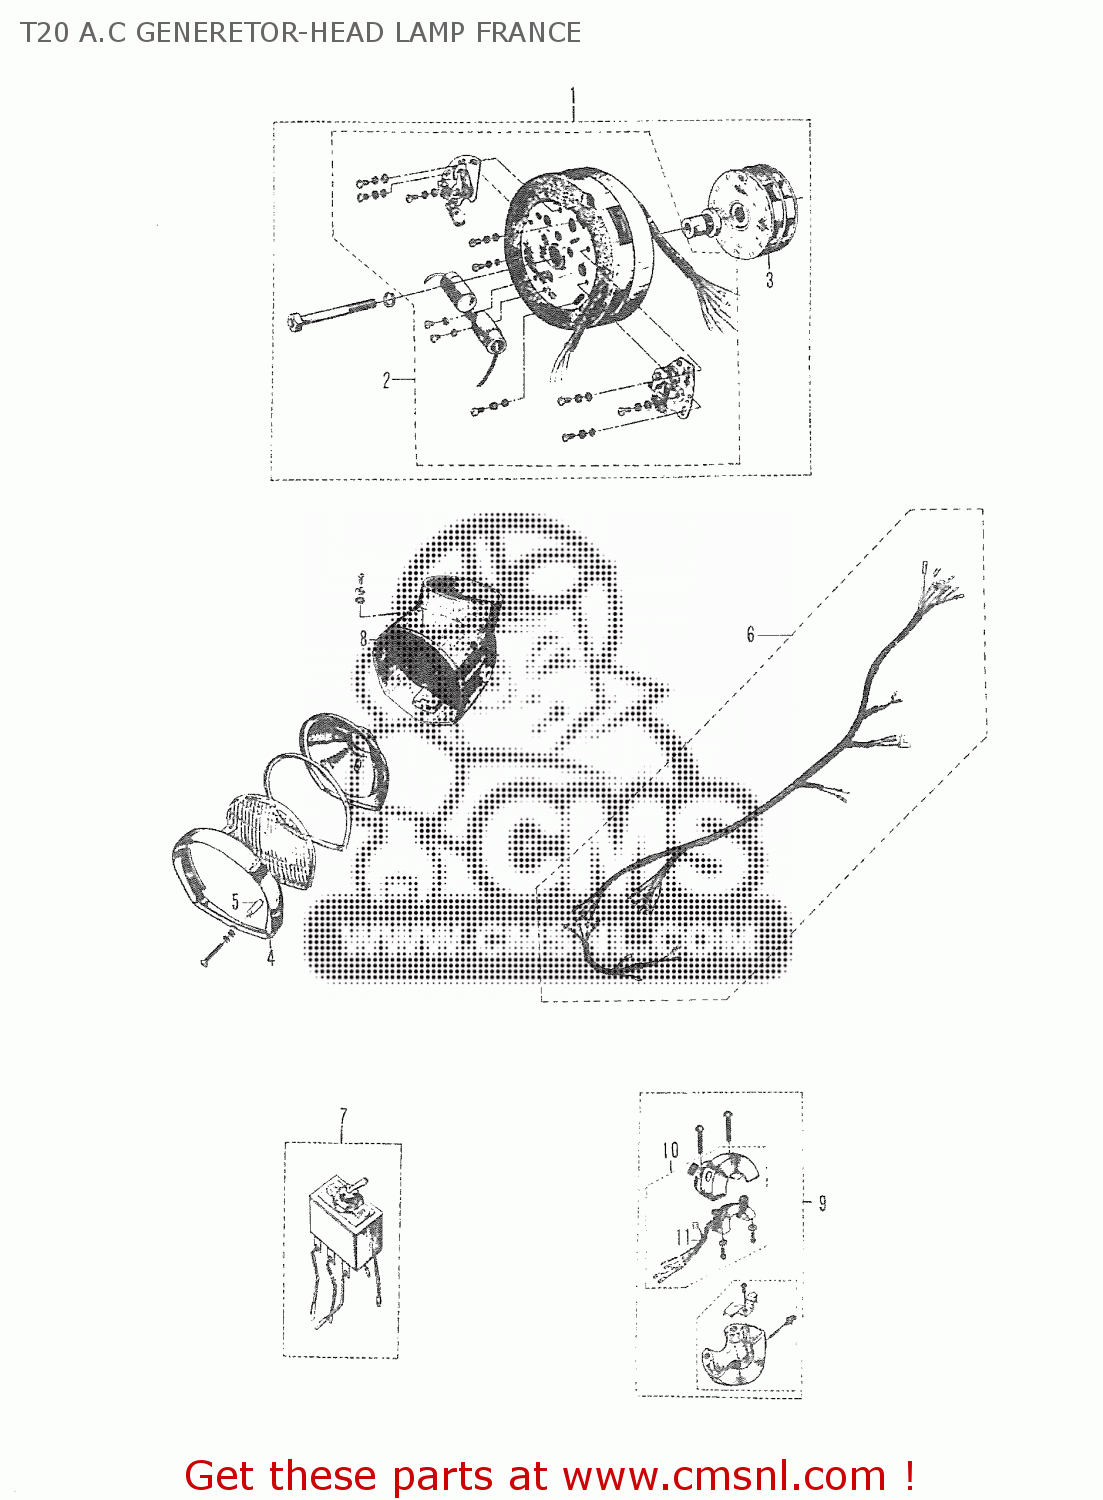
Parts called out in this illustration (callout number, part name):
1	A.C. GENERATOR ASS'Y
2	STATOR ASS'Y
3	ROTOR
4	HEAD LAMP RIM
5	HEAD LAMP RIM FITTING SPACER
6	MAIN WIRING HARNESS ASS'Y
7	CITY LAMP SWITCH ASS'Y
8	HEAD LAMP HOUSING
9	HANDLE SWITCH ASS'Y
10	HANDLE SWITCH UPPER COVER ASS'Y
11	WIRING HARNESS, SWITCH
